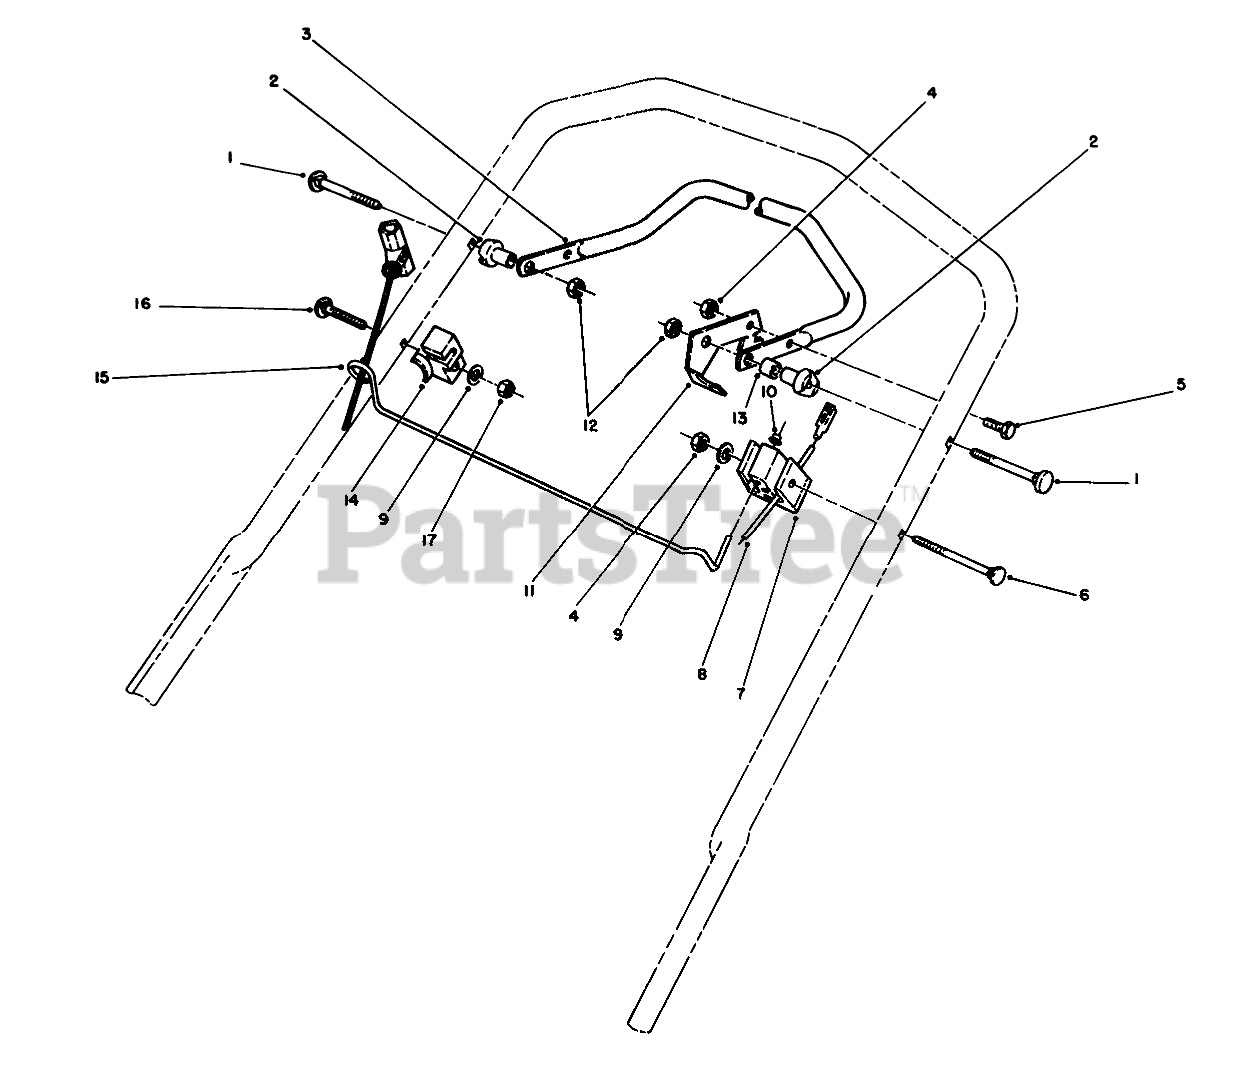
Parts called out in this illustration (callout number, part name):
1	5/16-18 X 2 HNDLE SCREW
2	SPACER-SUPPORT
3	Bar-Control
4	NUT-LOCK, NI
5	SCREW-HH
6	HANDLE SCREW
7	SUPPORT-CABLE
8	BRAKE CABLE
9	WASHER-FLAT
10	NUT-SPEED
11	LEVER-CONTROL
12	NUT-LOCK, NI
13	SPACER-NYLON
14	ROD CATCH
15	ROPE ROD PLATED
16	SCREW-HANDLE
17	NUT-HEX
